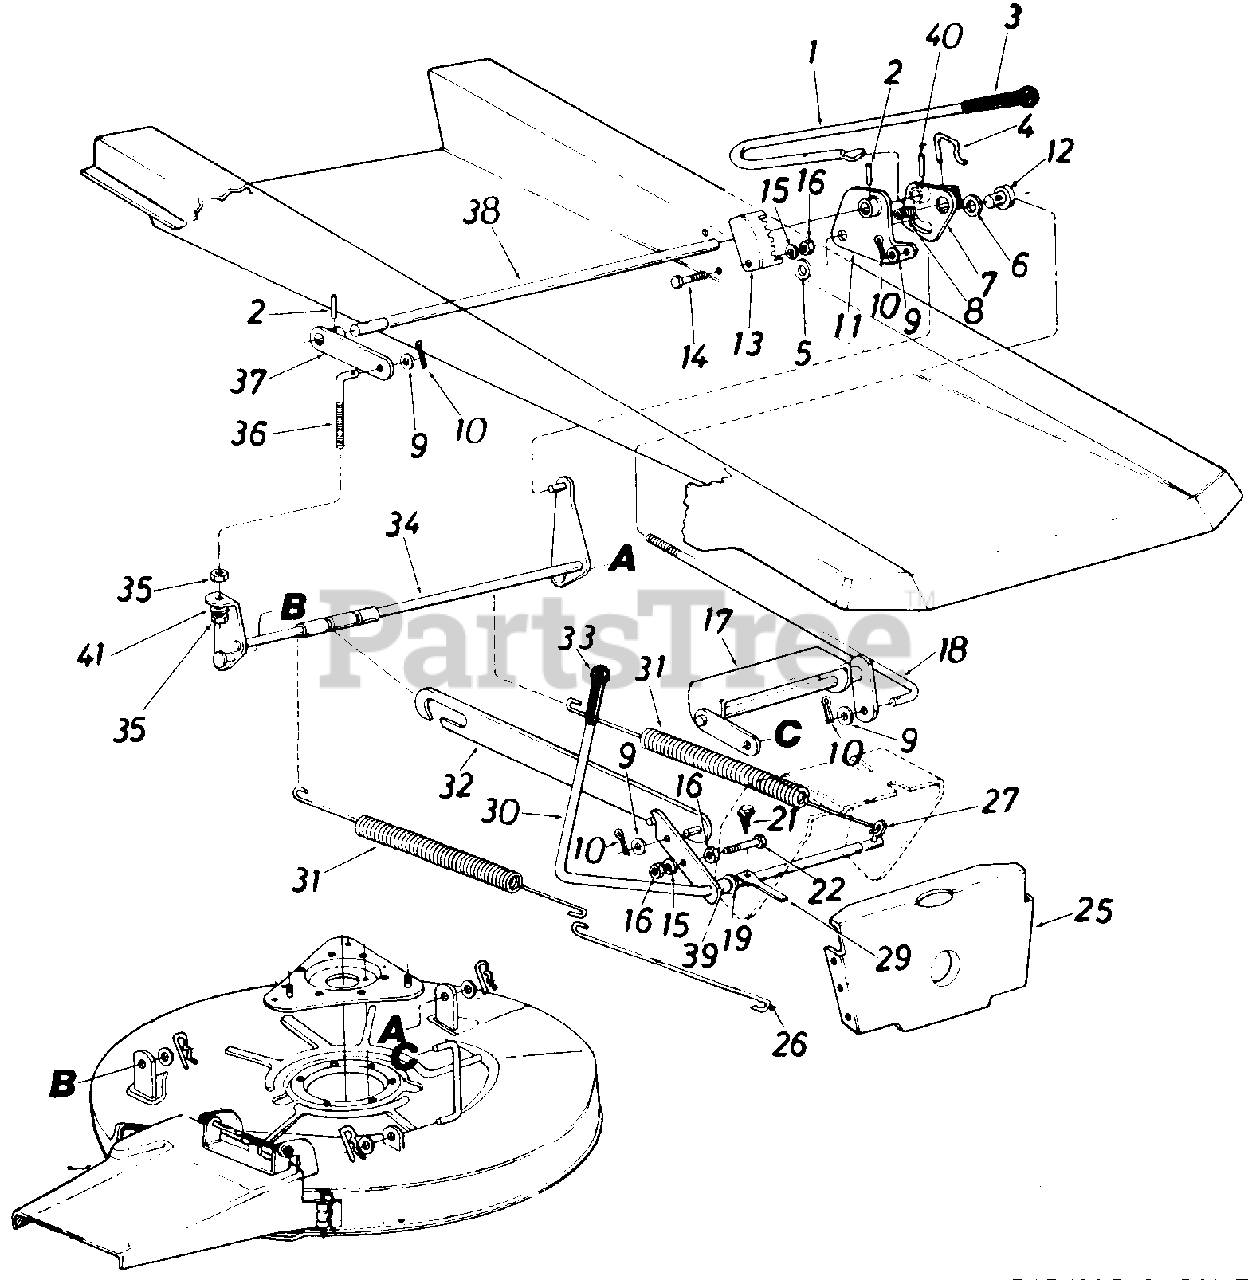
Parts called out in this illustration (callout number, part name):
1	Deck Lift Handle
2	Spring Pin Spir. 1/4" Dia. x 1.50" Lg.
4	Cotter Pin
5	Fl-Wash. 5/8" I.D. x 1.0" O.D. x .12
6	Fl-Wash. 5/8" I.D. x 1.25" O.D. x .60
7	Deck Lift Handle Brkt. Ass'y.
8	Compression Spring .50" O.D. x 1.04
9	Fl-Wash. .385" I.D. x .87" O.D. x .06
10	Cotter Pin 1/8" Dia. x 1.00"
11	Deck Lift Brkt. Ass'y.-L.H.
12	Adj. Ferrule-Deck Lift Handle
13	Index Bracket
14	Hex Bolt 5/16-18 x .75" Lg.
15	L-Wash. 5/16" I.D.
16	Hex Nut 5/16-18 Thd.
17	Deck Lift Ass'y. Front
18	Deck Lift Connecting Rod
19	Fl-Wash. .531" I.D. x .930"
21	Hex Wash. Hd. Self-Tap Scr. 1/4-20 x .50" Lg.
22	Hex Bolt 5/16-18 x 1.50" Lg.
25	Pivot Bar Bracket
26	Spring Hook
27	Spec. Clevis Pin .250" Dia.
29	Switch Actuator
30	Blade Engagement Lever Ass 'y .
31	Extension Spring .99" O.D. x 14.25" Lg.
32	Deck Drive Control Brkt. Ass'y.
33	G ri p
34	Deck Link Ass'y.-Rear
35	Hex Nut 3/8-16 Thd.
36	Deck Adj. Scr. 3/8-16 Thd.
37	Deck Lift Brkt. Ass'y.-R.H.
38	Rear Height Adj. Shaft
39	Sleeve .511" I.D. x .70" O.D. x.37" Lg.
40	Spring Pin Spir. 3/16" Dia. x 1.50" Lg.
41	L-Wash. 3/8" I.D.
